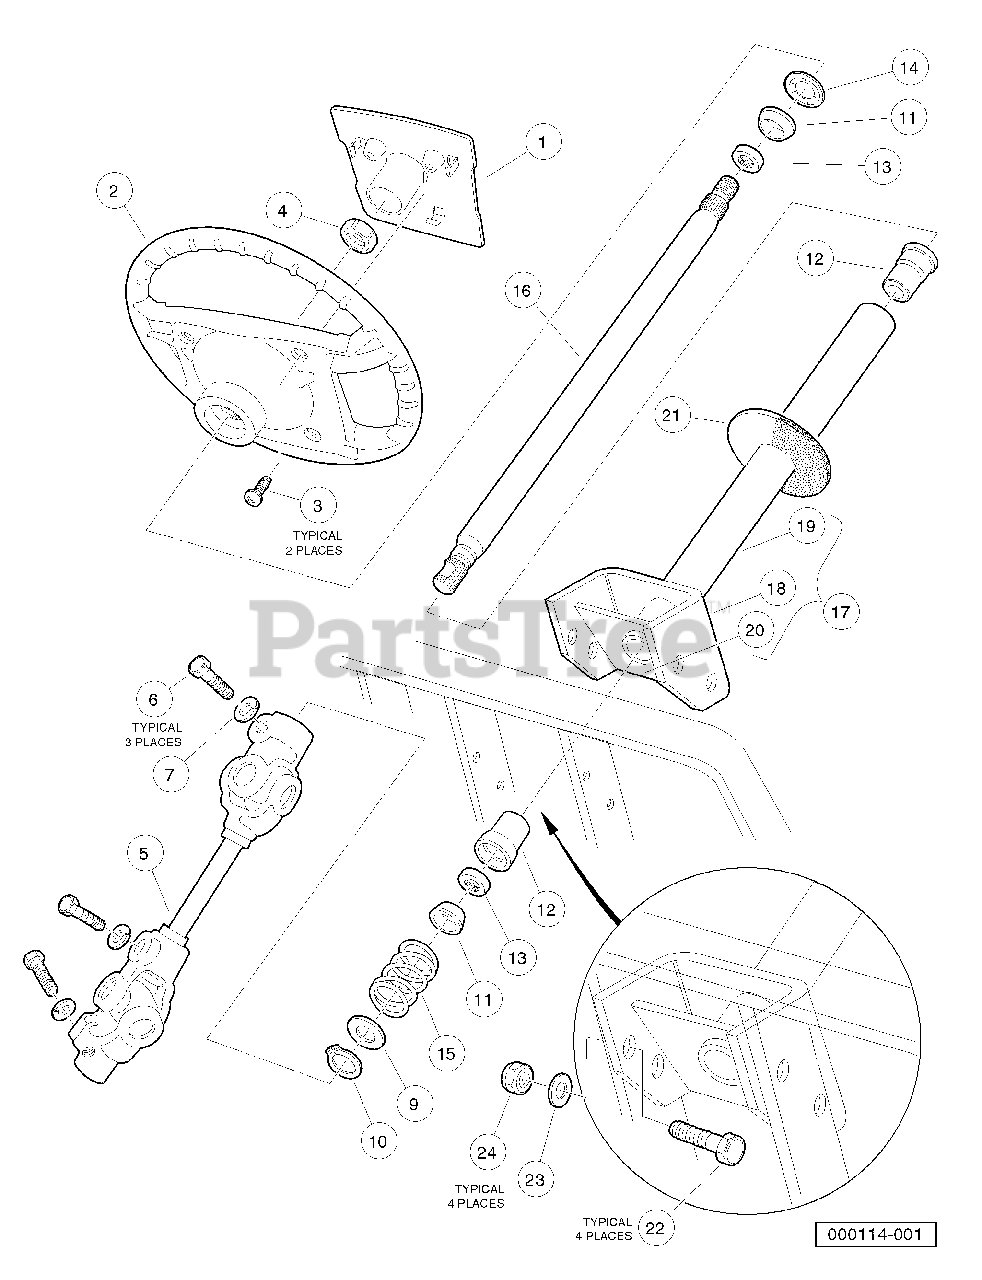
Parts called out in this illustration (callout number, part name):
1	Plate, Scorecard
2	Wheel, Steering
3	Screw, #12-14 X 0.625
4	Nut, 5/8-18 Nylon Insert Jam
5	Yoke Assembly
6	Bolt, Hex-Head, 8mm X 1.25 - 30
7	Lockwasher, 5/16 Split
8	Steering Column
9	Washer, 0.675 ID X 1.19 OD
10	Ring, 0.579 Internal Retaining
11	Wedge, Molded
12	Seat, Plastic Bearing
13	Bearing, Ball
14	Ring, Retaining
15	Spring, Steering Shaft
16	Shaft Steering Column
17	Column Weld Assy, Steering
18	Column Mtg Bracket
19	Steering Column
20	Steering Bracket Brace
21	Boot, Steering Column Round
22	Screw, 3/8-16 X 1.00 Hex-Head Cap
23	Washer, 3/8 Type A Flat
24	Locknut, 3/8-16 Hex
